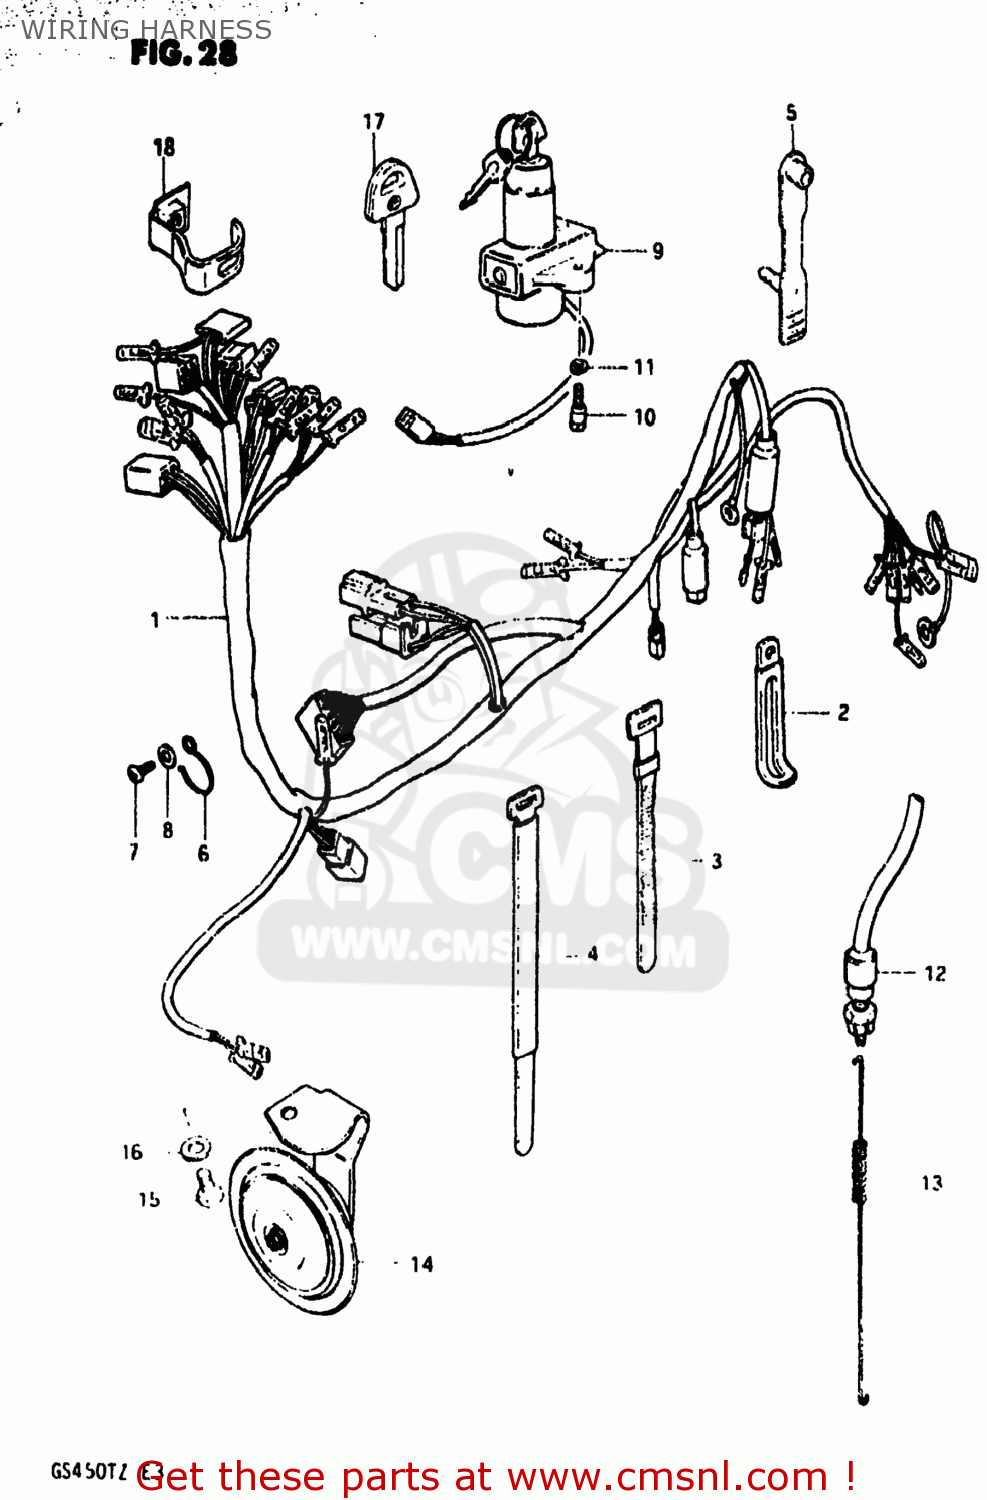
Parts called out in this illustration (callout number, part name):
1	HARNESS,WIRING
2	CLAMP
3	CLAMP
4	CLAMP
5	CLAMP,L:88
6	GUIDE,WIRING HARNESS
7	SCREW 6X12
8	WASHER
9	LOCK ASSEMBLY,STEERING
10	BOLT
11	LOCK WASHER
12	SWITCH ASSEMBLY,STOP LAMP
13	SPRING
14	HORN ASSEMBLY
15	BOLT 8X12
16	WASHER
17	KEY,BLANK
18	CLAMP,WIRING HARNESS
